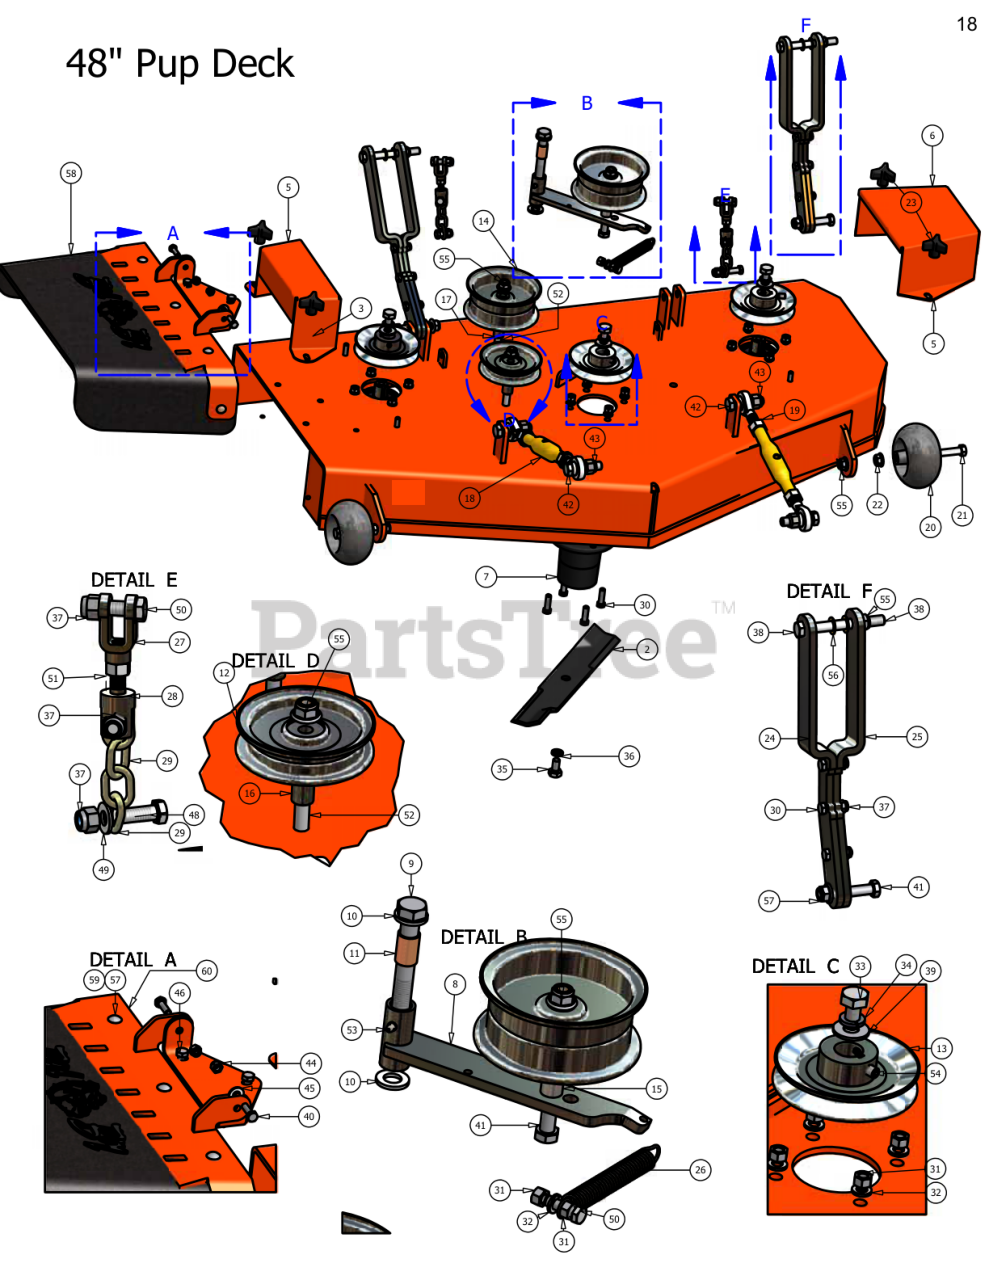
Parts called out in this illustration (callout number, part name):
1	48" Deck Belt
2	48" Fusion Blade
4	Discharge Chute Hanger
5	48" Spindle Cover
6	Spindle Cover
8	Deck Idler Arm
9	5/8" x 4" Hex Bolt
10	.635 ID Plastic Washer
11	5/8" ID x 1 1/8" Brass Bushing
12	4 3/4" Idler Pulley
13	5" Deck Pulley
14	5 3/4" Deck Idler Pulley
15	1 1/4" Pulley Spacer
16	1 1/2" Pulley Spacer
17	1 3/4" Pulley Spacer
18	Turnbuckle
19	3/4" Left Handed Nut
20	Anti-Scalp Rollers
21	1/2" x 4" Bolt (Grade 8)
22	1/2" Flange Nut
23	5/16" Knob
24	Deck Support Arm (left)
25	Deck Support Arm (Right)
26	Deck Idler Spring
27	Female Yoke
30	3/8" x 1 1/4" Hex Bolt
31	3/8" Hex Nut
32	3/8" Lock Washer
33	1/2" x 1 1/2" Bolt Fine Threaded
34	1/2" Lock Washer
35	5/8" x 1.5" Fine Threaded Bolt
36	5/8" Lock Washer
37	3/8" Nylock Nut
38	1/2" x 4 1/2" Bolt
39	1/2" Cup Washer
40	5/16" x 1" Hex Bolt
41	1/2" x 2 1/2" Hex Bolt
42	5/8" x 2 1/2" Hex Bolt
43	5/8" Nylock Nut
44	5/16" Nylock Nut
45	.360 ID Plastic Washer
46	3/8" x 3/4" Hex Bolt
47	3/8" Flange Nut
48	3/8" x 1" Hex Bolt
49	3/8" Flat Washer
50	3/8" x 1 1/2" Hex Bolt
51	3/8" Fine Threaded Jam Nut
52	1/2" x 3 1/2" Bolt
53	Grease Fitting (Drive-In Type)
54	3/8" Set Screw
55	1/2" Flange Lock Nut
56	1/2" Brass Washer
57	5/16" x 1 1/2" Carriage Bolt
58	Rubber Side Discharge
59	5/16" Nylock Flange Nut
60	2007 Hanger Plate
61	2007 Lower Hanger Plate
